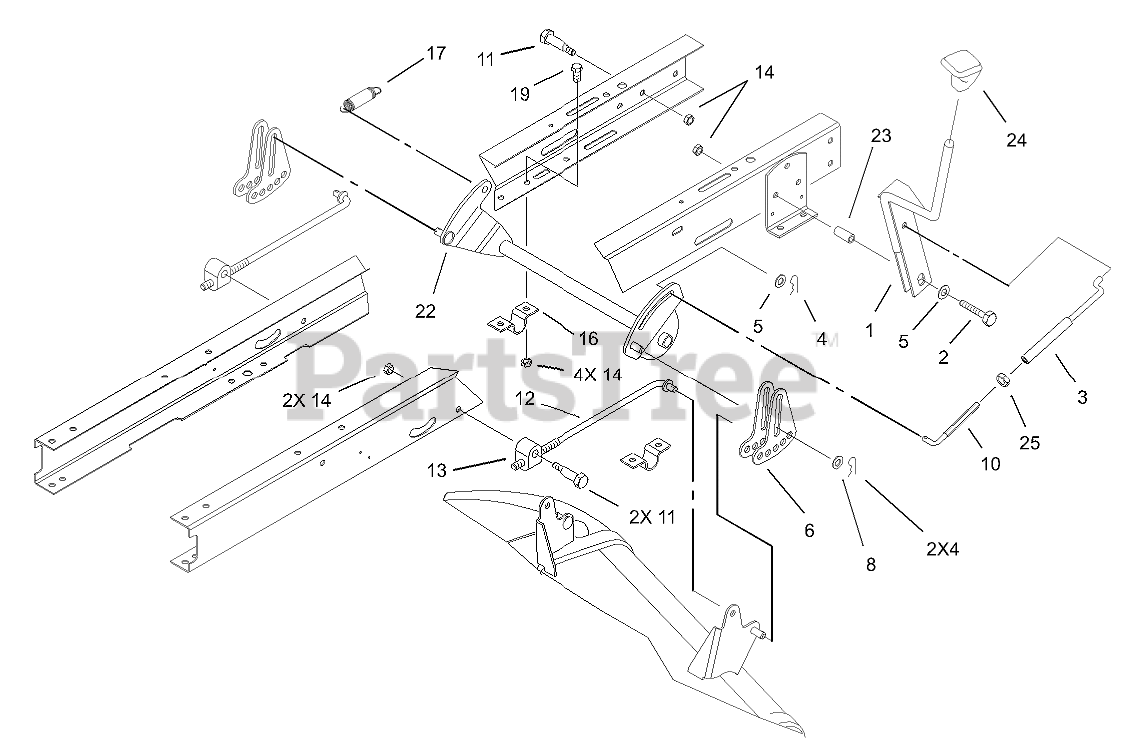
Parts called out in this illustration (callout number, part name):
1	HOC LEVER ASM
2	SCREW-HH
4	PIN-COTTER
5	WASHER-FLAT
6	LINK-ADJUSTING, HOC
8	WASHER-HARDENED
10	LINK-HOC
11	SCREW-SHOULDER, HH
12	ROD-HANGER, REAR
13	TRUNNION-HOC
14	NUT-LOCK, NI
16	CLAMP-PIVOT, HOC
17	SPRING-EXTENSION
19	SCREW-HH
22	PIVOT-HOC
23	SPACER
24	KNOB-SHIFT
25	NUT-JAM
